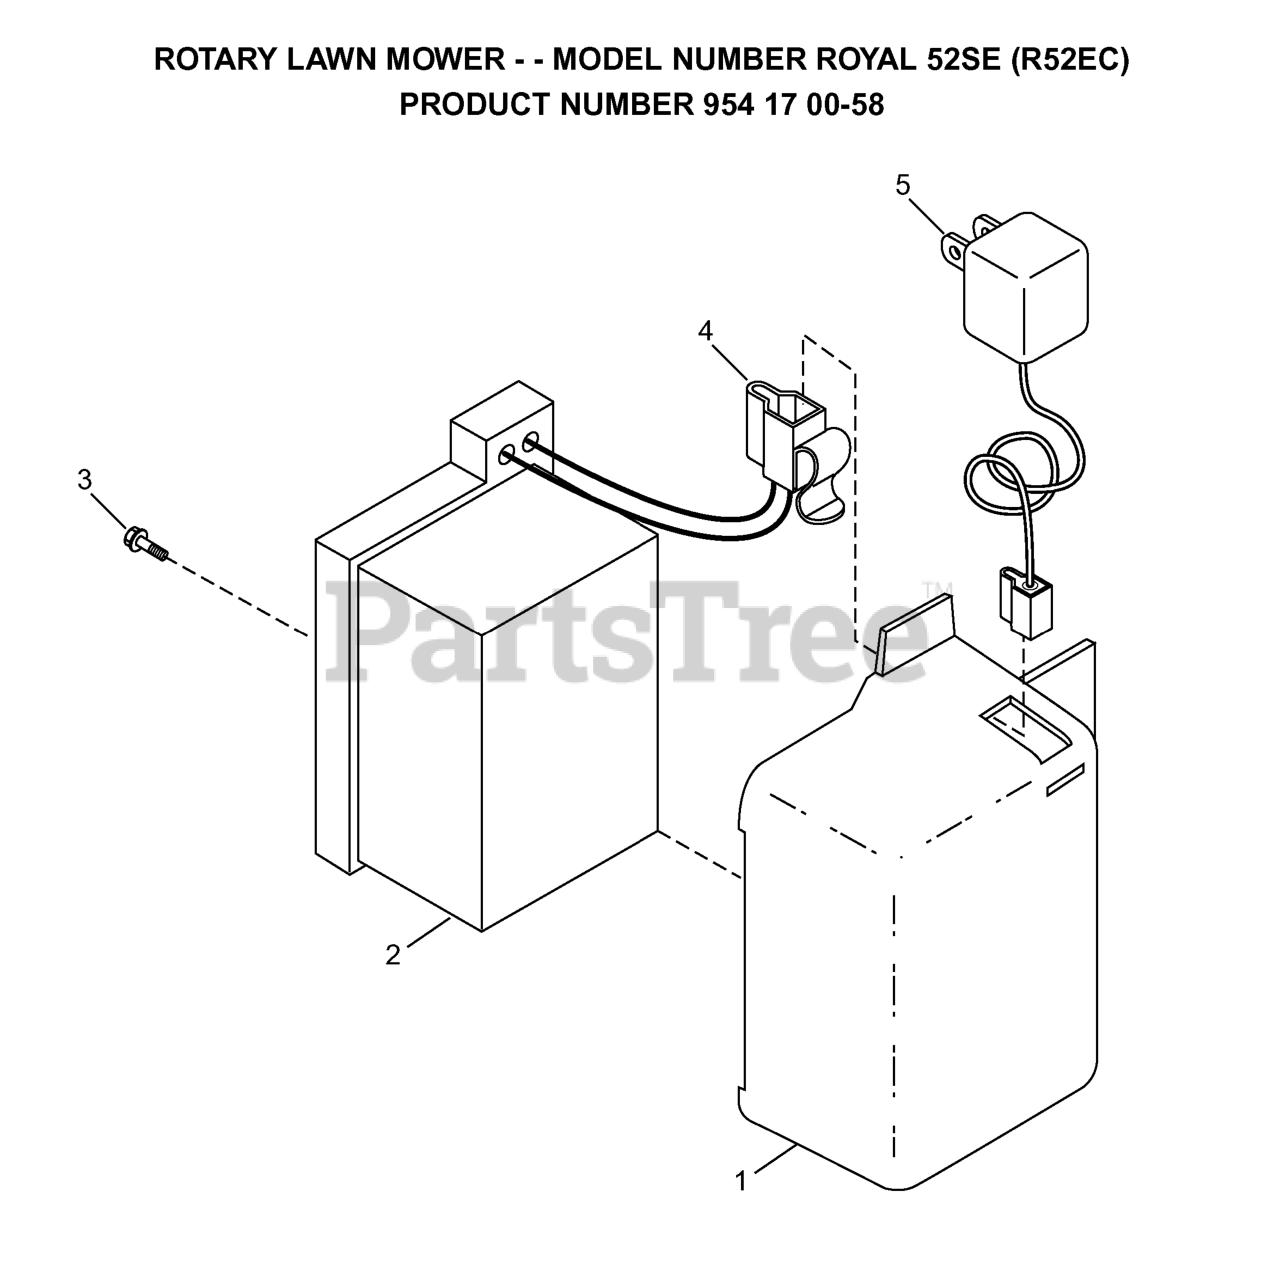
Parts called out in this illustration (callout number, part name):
2	KIT BATTERY REPL
3	SCREW.HX.13X.750
4	CONNECTOR PM
5	BATTERY CHARGER
